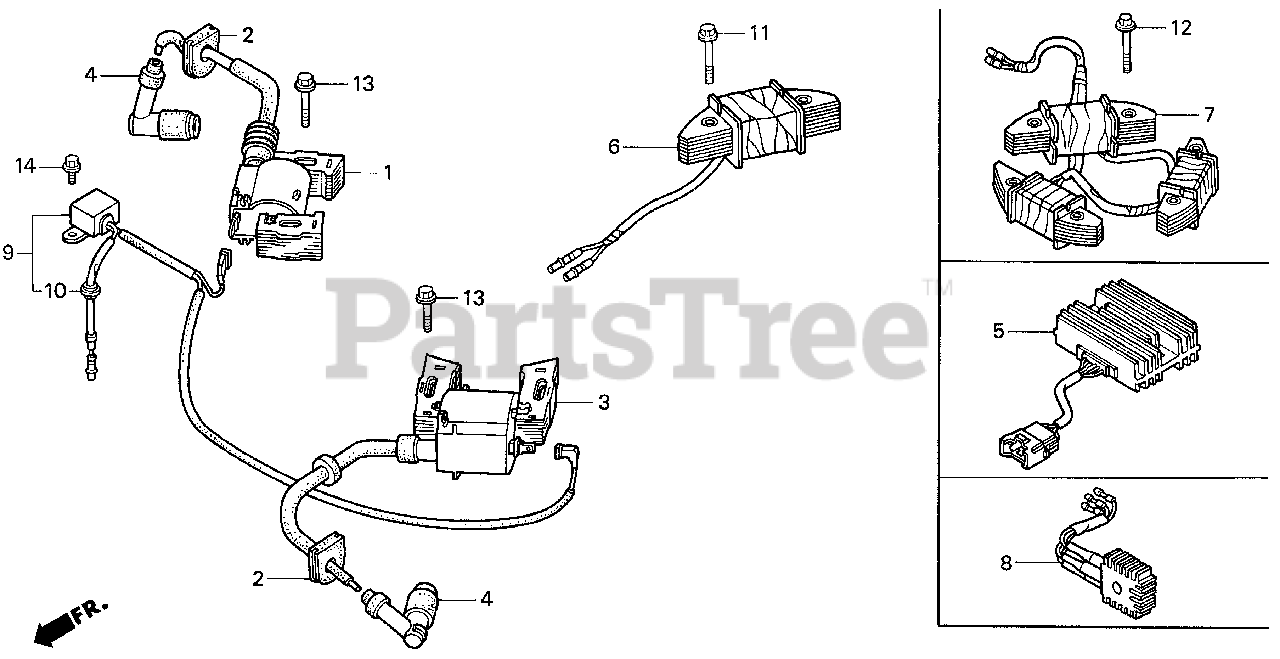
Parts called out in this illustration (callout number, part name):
1	COIL ASSY., R. IGNITION
2	GROMMET, IGNITION WIRE
3	COIL ASSY., L. IGNITION
4	CAP ASSY., NOISE SUPPRESSOR
6	COIL ASSY., CHARGE (12V/3A)
8	RECTIFIER ASSY.
9	DIODE ASSY., ENGINE STOP
10	GROMMET, TOOL
11	BOLT, FLANGE (6X35)
13	BOLT, FLANGE (6X25)
14	BOLT, FLANGE (6X8)
